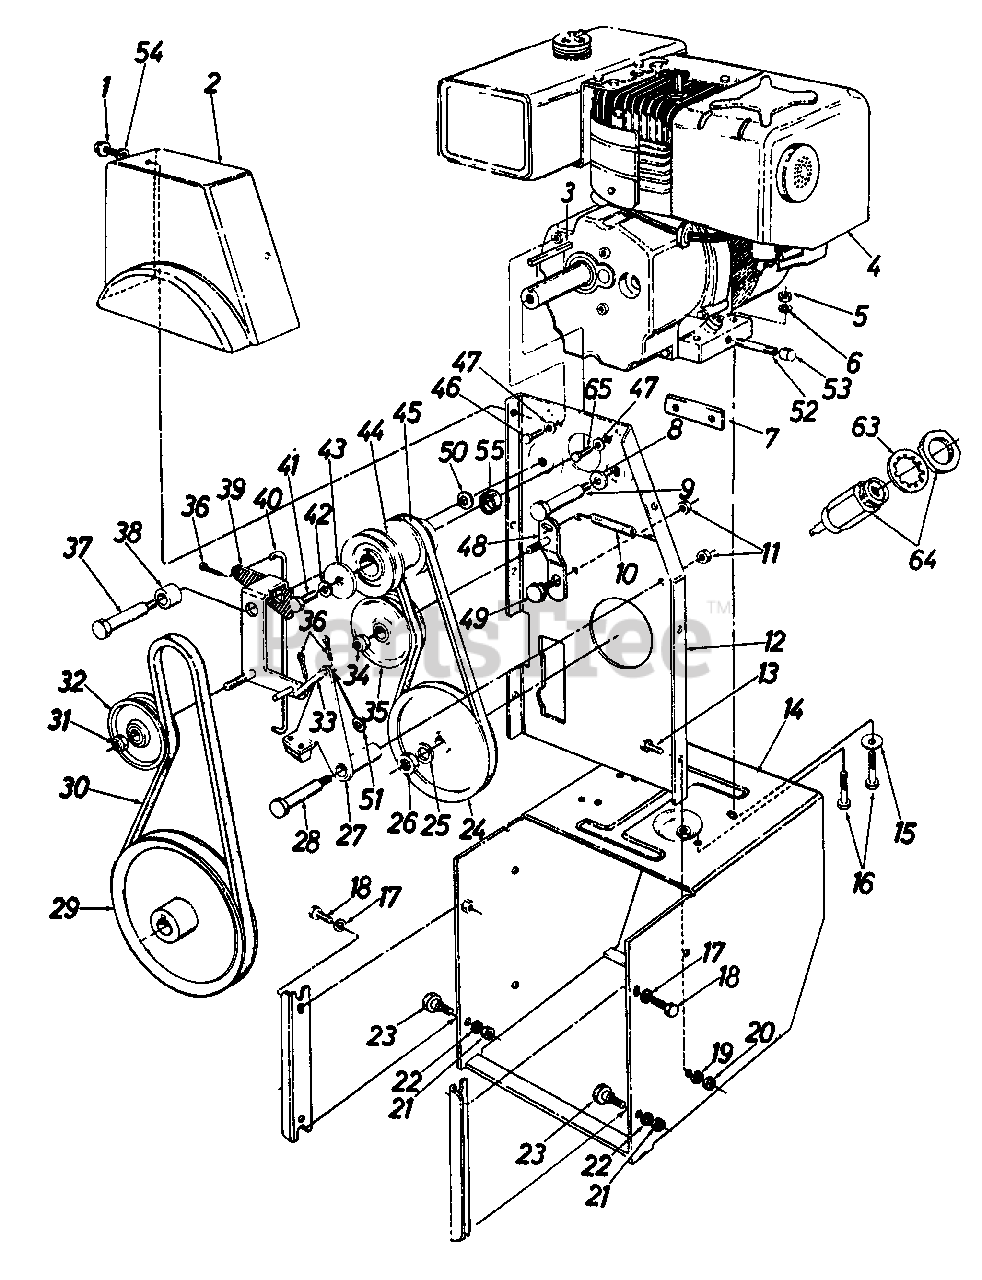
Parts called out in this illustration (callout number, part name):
1	Hex Wash. Self-Tap Scr. 5/16-24 x .50" Lg.
2	Belt Cover
3	Sq. Key 1/4" X 1.50" Lg.
4	Engine
5	Hex Nut 5/16-18 Thd.
6	L-Wash. 5/16" Scr.
7	Engine Spacer Plate
8	Bell-Wash. .40 I.D. x .88 O.D.
9	Shld. Scr. .498" Dia. x 3.00" Lg.
10	Ext. Spring .38 O.D. x 3.18" Lg.
11	Hex Cent. L-Nut 3/8-16 Thd.
12	Engine Brkt. Ass'y.
13	Hex Sems Scr. 5/16-18 x .75" Lg.*
14	Frame Ass'y.
15	Fl-Wash. .345 I.D. x .75 O.D. x .060
16	Hex Scr. 5/16-18 x 1.75" Lg.*
17	L-Wash. 3/8" Scr. H.D.
18	Pilot Scr. 3/8-16 x .88" Lg.
19	L-Wash. 5/16" Scr.*
20	Hex Nut 5/16-18 Thd.*
21	Hex Nut 3/8-16 Thd.*
22	L-Wash. 3/8" Scr. H.D.
23	Shld. Scr. .498" Dia. x .340" Lg.
24	V-Pulley .628 I.D. x 7.50 O.D.
25	L-Wash. for 5/8" Scr.*
26	Hex Ins. Jam L-Nut 5/8-18 Thd.
27	Brake Brkt. Ass'y.
28	Shld. Scr. .498" Dia. x 2.00" Lg.
29	V-Pulley .875 I.D. x 10.12 O.D.
30	"V"-Belt 1/2 " X 45.0" Lg.
31	Hex Ins. Jam L-Nut 3/8-24 Thd.
32	Fl-ldler w/Flanges 3.0 O.D.
33	Brake Linkage Ass'y.
34	Hex Ins. Jam L-Nut 3/8-24 Thd.
35	3.0" O.D. Fl-ldler w/Flanges
36	Int. Cot. Pin 5/16" Dia.
37	Shld. Scr. .625 Dia. x 2.750" Lg.
38	Spacer .75 O.D. x 1.00" Lg.
41	Hex Bolt 3/8-24 x 1.25" Lg.
42	L-Wash. 3/8" Scr. H.D.
43	Fl-Wash.
44	Engine Pulley-Double Groove
45	"V"-Belt 3/8 x 35.5 Lg.
46	Hex Bolt 5/16-24 x 1.0" Lg.*
47	Bell-Wash. .345 I.D. x .88 O.D. x .060
48	Drive Idler Brkt. Ass'y.
49	Shld. Scr.-.625" Dia. x .170" Lg.
50	Bell-Wash. .40 I.D. x 1.12 O.D.
51	Fl-Wash. .34 I.D. x .750 O.D. x .05
52	Pipe Nipple-3/8-18 x 3.0" Lg.
53	Cap Oil Drain
54	Fl-Wash. .340 I.D. x .62 O.D. x .62
55	Spacer 1.0" I.D. x 1.32" O.D. x .4"
63	L-Wash. 5/8" I.D.
64	Ignition Switch
65	Hex Wash. Hd. Self-Tap Scr. 5/16-24 x .50" Lg.
